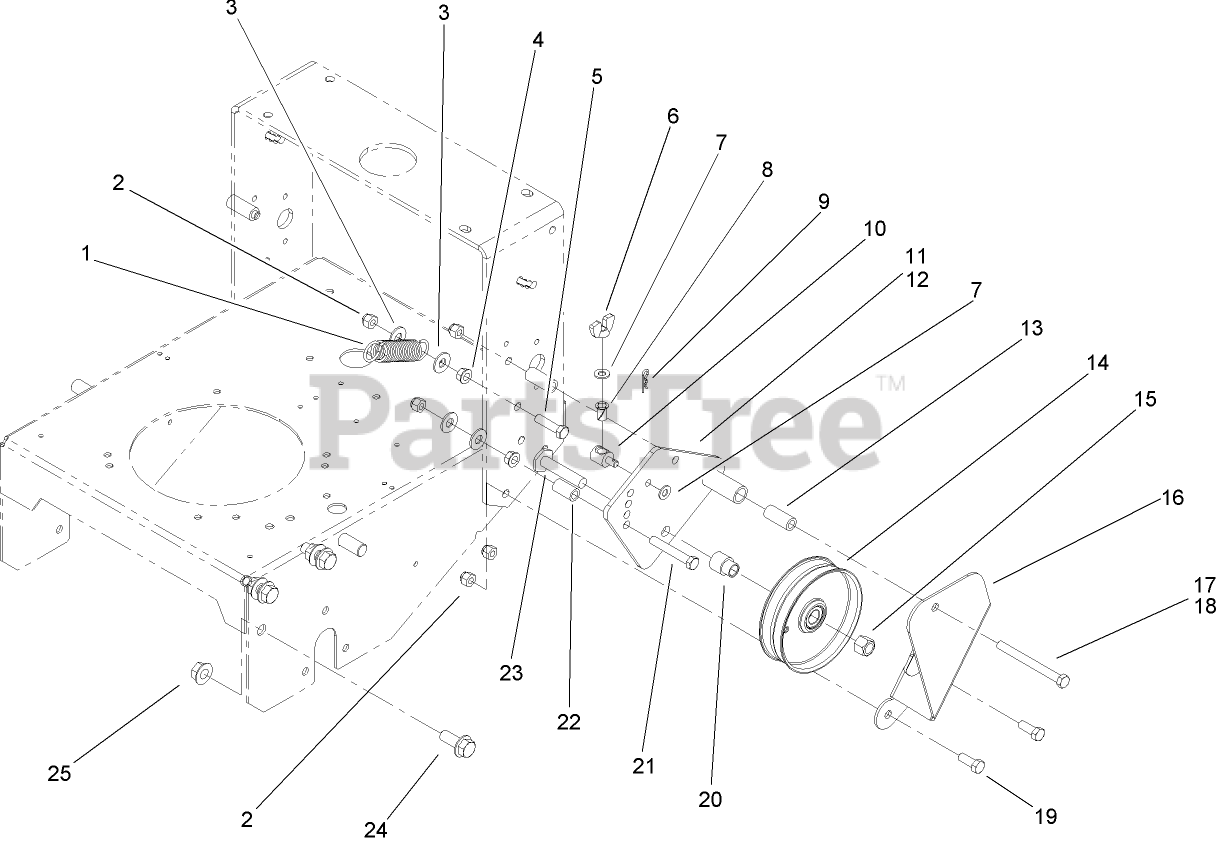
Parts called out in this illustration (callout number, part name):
1	SPRING-EXTENSION
2	NUT-LOCK, NI
3	WASHER-FLAT
4	NUT-FLANGE
5	SCREW-HH
6	NUT-WING
7	WASHER-PLAIN
8	BUSHING-NYLON
9	PIN-COTTER
10	FITTING-ROD
11	LH IDLER BRACKET ASM
12	RH IDLER BRACKET ASM
13	SPACER-PIVOT, IDLER
14	PULLEY-IDLER
15	NUT-LOCK, NI
16	BRACKET-SUPPORT, LH
17	BRACKET-SUPPORT, RH
18	SCREW-HH
19	SCREW-HH
20	SPACER-PULLEY
21	SCREW-HH
22	SPACER
23	SCREW-LEVELER
24	SCREW-HHF
25	NUT-HF
